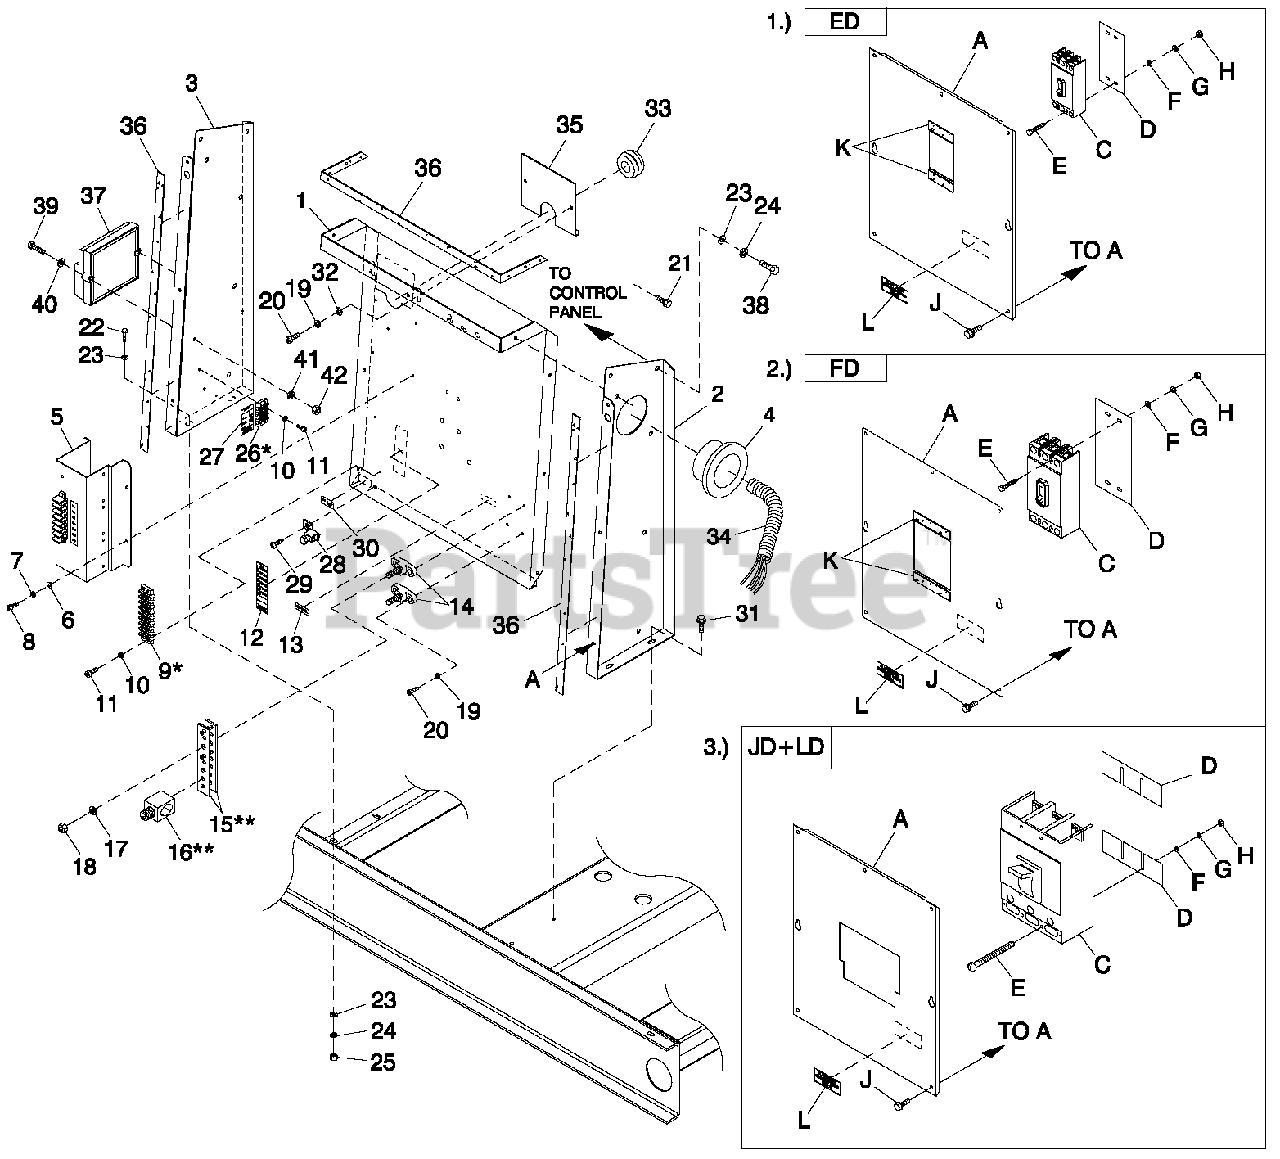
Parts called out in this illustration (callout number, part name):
1	PAN CB CONN BOX
1	UL CIRCUIT BREAKER (ED)
2	STAND RH CONTROL
2	UL CIRCUIT BREAKER (FD)
3	STAND LH CONTROL
3	UL CIRCUIT BREAKER (JD+LD)
4	BUSHING SNAP SB-2.5-31
5	ASSY PCB INTERFACE 1PH 240V
6	WASHER FLAT M4
7	WASHER LOCK #8-M4
8	SCREW PHTT M4-0.7X 10 ZYC
9	BLOCK TERM 20A 8 X 6 X 1100V
10	WASHER LOCK #6
11	SCREW PHTT #6-32 X 1/2 ZYC
12	DECAL CPL CUST CONN H CTRL
13	DECAL NEUTRAL
14	JUNCTION BLOCK 3/8-16
15	BUS BAR NEUTRAL BLOCK 390
16	LUG SLDLSS 600/250-1/0 X 1/4-28
17	WASHER LOCK 3/8
18	NUT HEX 3/8-16 STEEL
19	WASHER LOCK M5
20	SCREW PHTT M5-0.8X 16 ZYC
21	SCREW THF M6-1 X 16 N WA Z/JS
22	SCREW HHC M6-1.0 X 20 G8.8
23	WASHER FLAT 1/4-M6 ZINC
24	WASHER LOCK M6-1/4
25	NUT HEX M6X 1.0 G8 YEL CHR
26	BLOCK TERM 20A 6 X 3 X 1100V
27	DECAL CUST CONN 120V UTILITY
28	LUG SLDLSS #6-14 X 13/64CU
29	SCREW HHTT #10-32 X 3/8 CZ
30	DECAL GROUND LUG
31	SCREW HHTT M6-1.0 X 16ZYC
32	WASHER FLAT M5
33	GROMMET 1.25 X .25 X .75
34	CONDUIT FLEX 2.0" ID
35	PLATE WIRE SNGLGALV
36	TAPE ELEC 1/2 FOAM (AS REQ'D)
37	ASSY PCB HSB CTRL IGN MODULE
38	SCREW HHC M6-1.0X 16 G8.8
39	SCREW PPHM #10 /32X2
40	WASHER FLAT #10 ZINC
41	WASHER LOCK #10
42	NUT HEX #10-32 STEEL
A	COVER ED CB STAND C3
C	CB0090A 3P 480V S ED4 LL
D	INSULATOR CB S(ED-3P)
E	SCREW RHM #10-32 X 4-1/2
F	WASHER FLAT #10 ZINC
G	WASHER LOCK #10
H	NUT HEX #10-32 STEEL
J	SCREW THF M6-1 X 16 N WA Z/JS
K	TAPE ELEC 1/2 FOAM (AS REQ'D)
L	DECAL CUSTOMER CONNECT INSIDE
A	COVER FDCB STAND C3
C	CB 0200A 3P 600V S FD6 LL
D	INSULATOR CB FD FRAME 30MIL
E	SCREW SHC 1/4-20 X 4 G8.8 NZ
F	WASHER FLAT 1/4-M6 ZINC
G	WASHER LOCK M6-1/4
H	NUT HEX 1/4-20 STEEL
A	COVER JD/LDCB STAND C3
C	CB 0300A 3P 600V S JD6 LL
D	INSULATOR CIRCUIT BR. JD/LD
E	SCREW RHM 1/4-20 X 3
